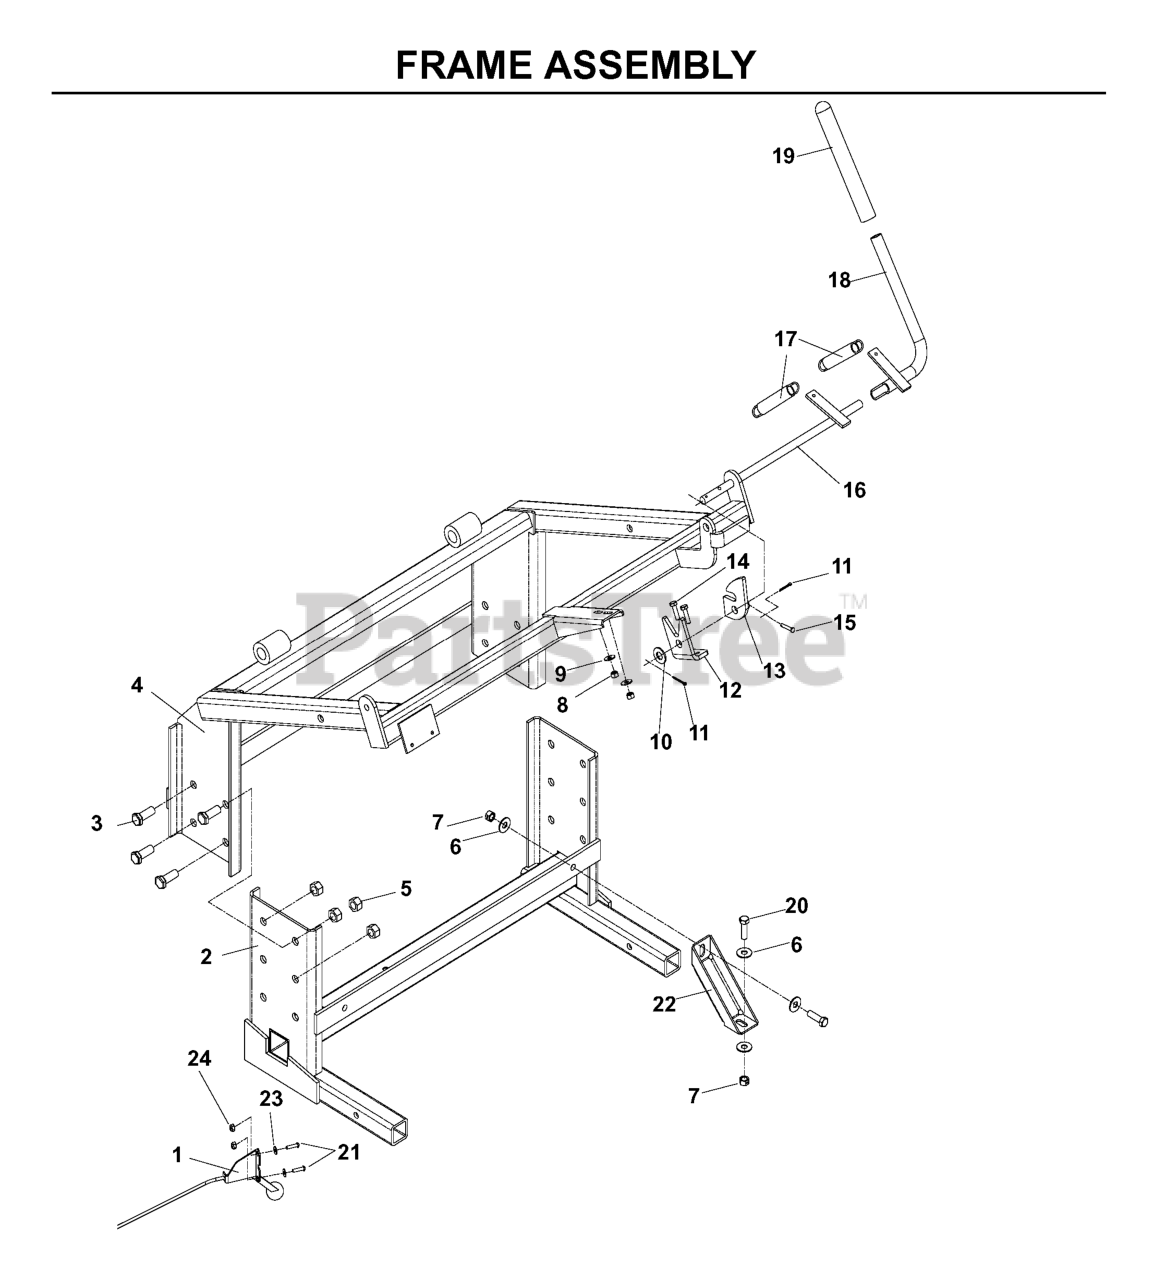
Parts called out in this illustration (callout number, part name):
1	THROTTLE CABLE
2	LOWER FRAME
3	BOLT 1/2 X 1.25
4	UPPER FRAME
5	NUT 1/2 NYLOC
6	FLAT WASHER 3/8
7	NUT 3/8 NYLOC
8	Nut, Hex, Nylon Lock, 1/4"-20
9	WASHER, 1/4
10	FLAT WASHER 1/2"
11	PIN, COTTER, 3/32 X 3/4
12	LATCH BASE
13	WELDMENT, LATCH CATCH BLK
14	BOLT, 1/4-28 X 1
15	PIN, CLEVIS, 3/16 X 1
17	SPRING
18	RELEASE LEVER
19	GRIP
20	BOLT 3/8 X 1.25
21	SCREW, #10-24 X 3/4, RD. HD., SLOTTED
22	HITCH BRACKET
23	FLAT WASHER #10
24	Nut, Hex, Nylon Lock, #10-24
